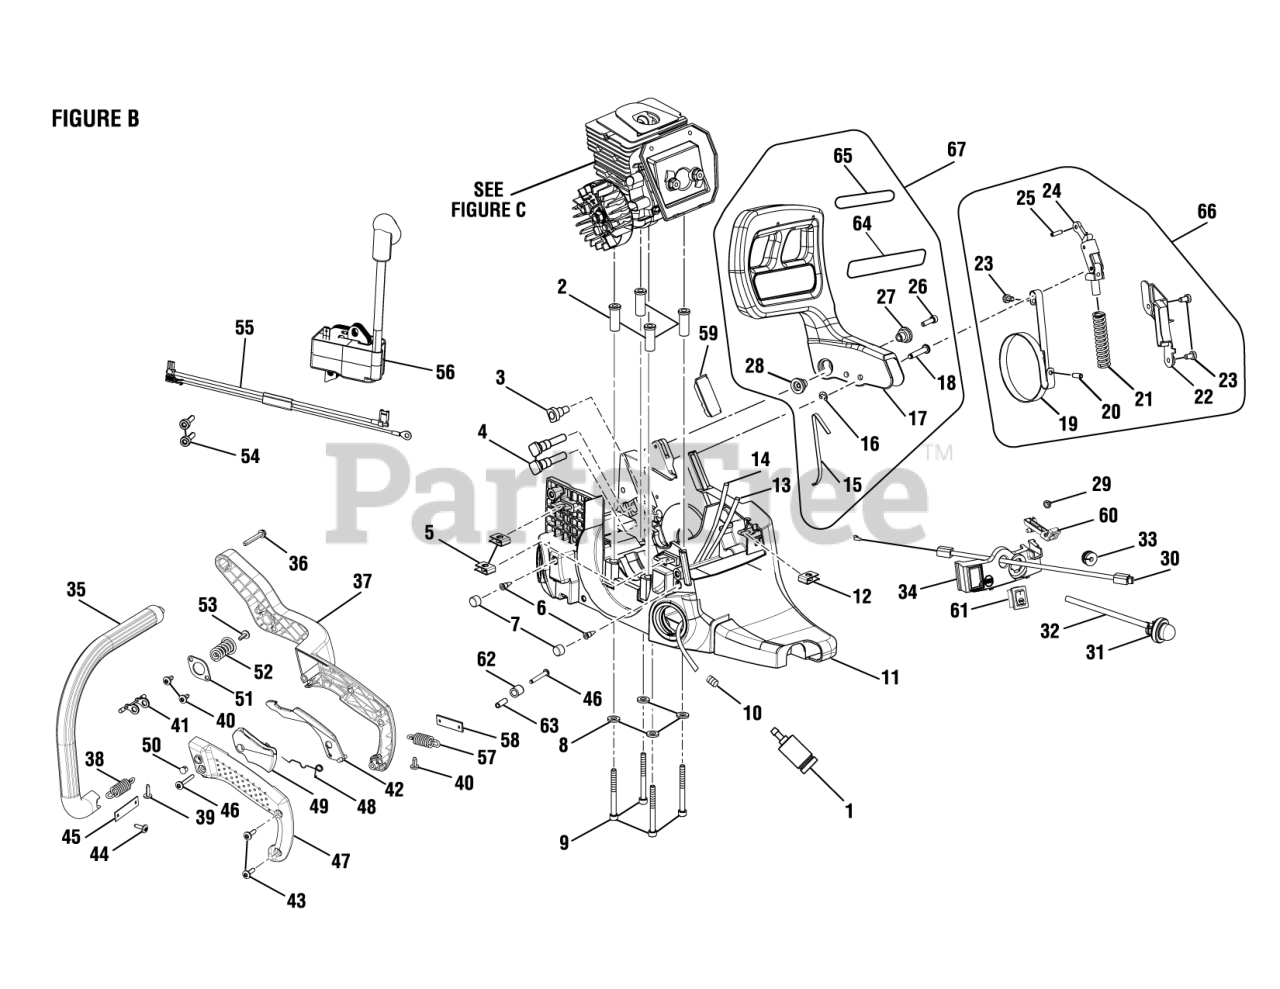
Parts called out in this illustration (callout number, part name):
1	FILTER FUEL
2	INSERT, SPACER
3	GROMMET, OIL OUTLET
4	BOLT, GUIDE BAR
5	NUT, SPEED
6	VENT, TANK
10	CLAMP, HOSE
12	NUT, SPEED
13	HOSE, FUEL
14	HOSE, FUEL (RETURN)
15	SPRING, HAND GUARD
16	RING, RETAINING
17	LEVER, CHAIN BRAKE
18	PIN, HAND GUARD ACTUATING
19	BAND, BRAKE
20	PIN, SPRING
21	SPRING, COMPRESSION
22	COVER, CHAIN BRAKE
24	ASSY., CHAIN BREAK LINK
25	PIN, SPRING
27	PIVOT, RIGHT HAND
28	PIVOT, LEFT HAND
29	PIN, HAIR
30	CABLE, THROTTLE
31	BULB, PRIMER
32	HOSE, FUEL (PRIMER)
33	GROMMET, SPLIT
34	PANEL, CONTROL
35	HANDLE, FRONT
37	HANDLE, REAR
41	LIMITER, UPPER ISOLATOR SPRING
42	LOCKOUT, THROTTLE
45	RETAINER, SPRING
47	COVER, HANDLE
48	SPRING, TORSION
51	PLATE, ISOLATOR
52	SPRING, ISOLATOR
55	ASSY., WIRING HARNESS
56	MODULE, IGNITION
58	RETAINER, SPRING
60	LEVER, CHOKE
61	SWITCH, STOP
63	SPACER, SPRING SCREW
64	LABEL, WARNING ICON
65	LABEL, PULL TO RELEASE BRAKE
66	KIT, BRAKE BAND
67	ASSY., CHAIN BRAKE LEVER
